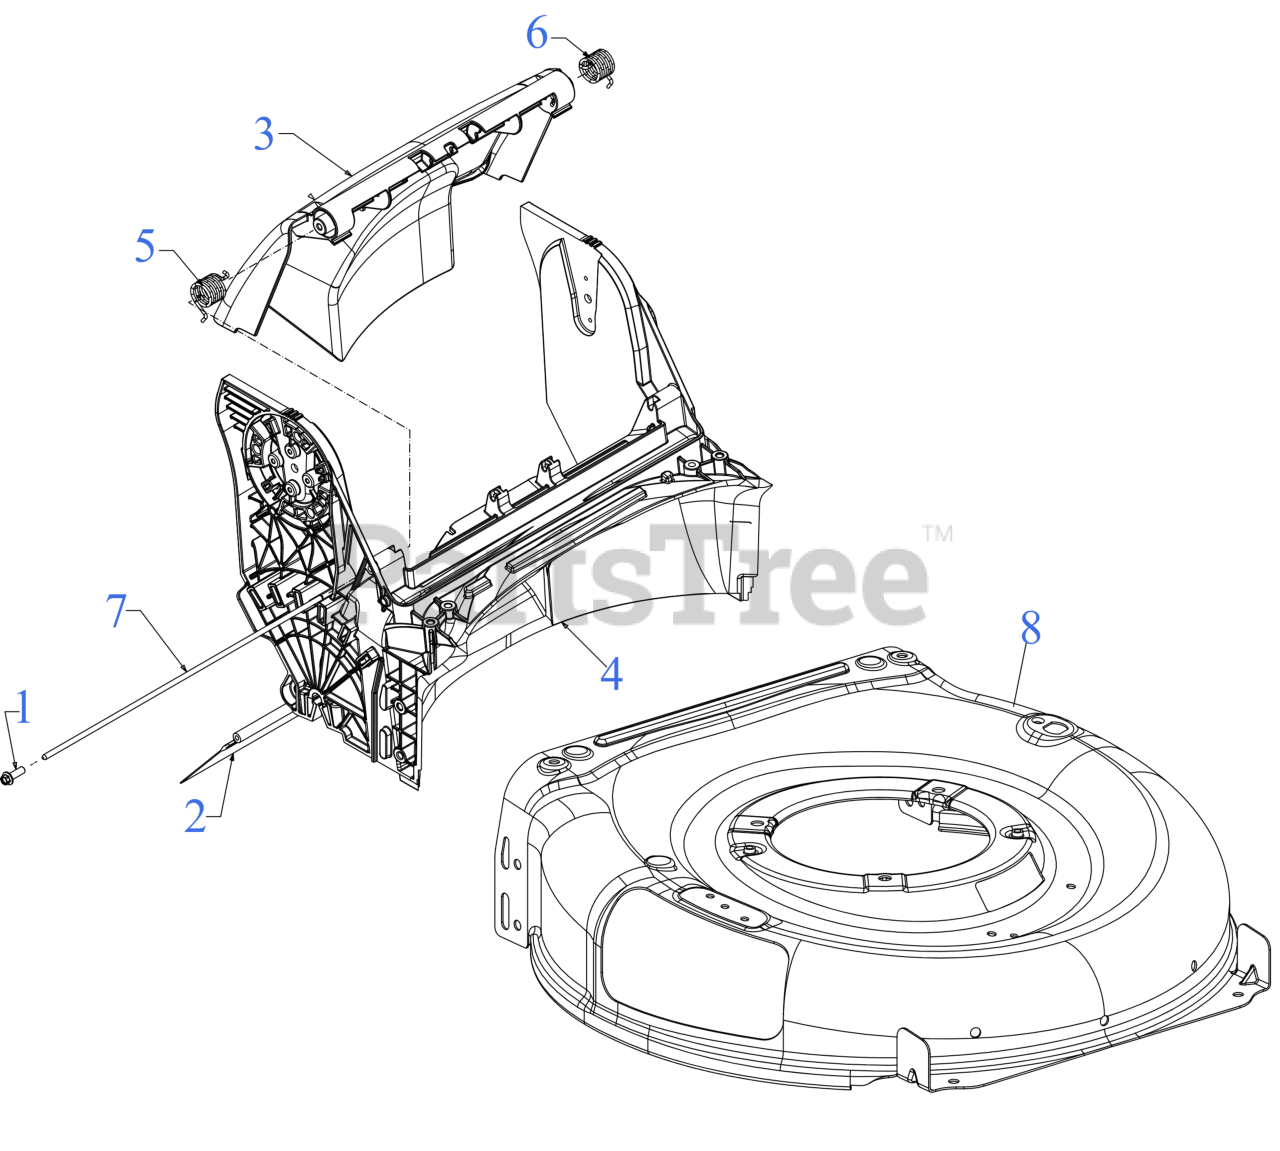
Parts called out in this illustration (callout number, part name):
1	SCREW 1/4 x .750
2	TRAILSHIELD
3	REAR BAFFLE ASSEMBLY
4	REAR BAFFLE ASSEMBLY
5	TORSION SPRING (RH)
6	TORSION SPRING (LH)
7	REAR DOOR PIVOT ROD
